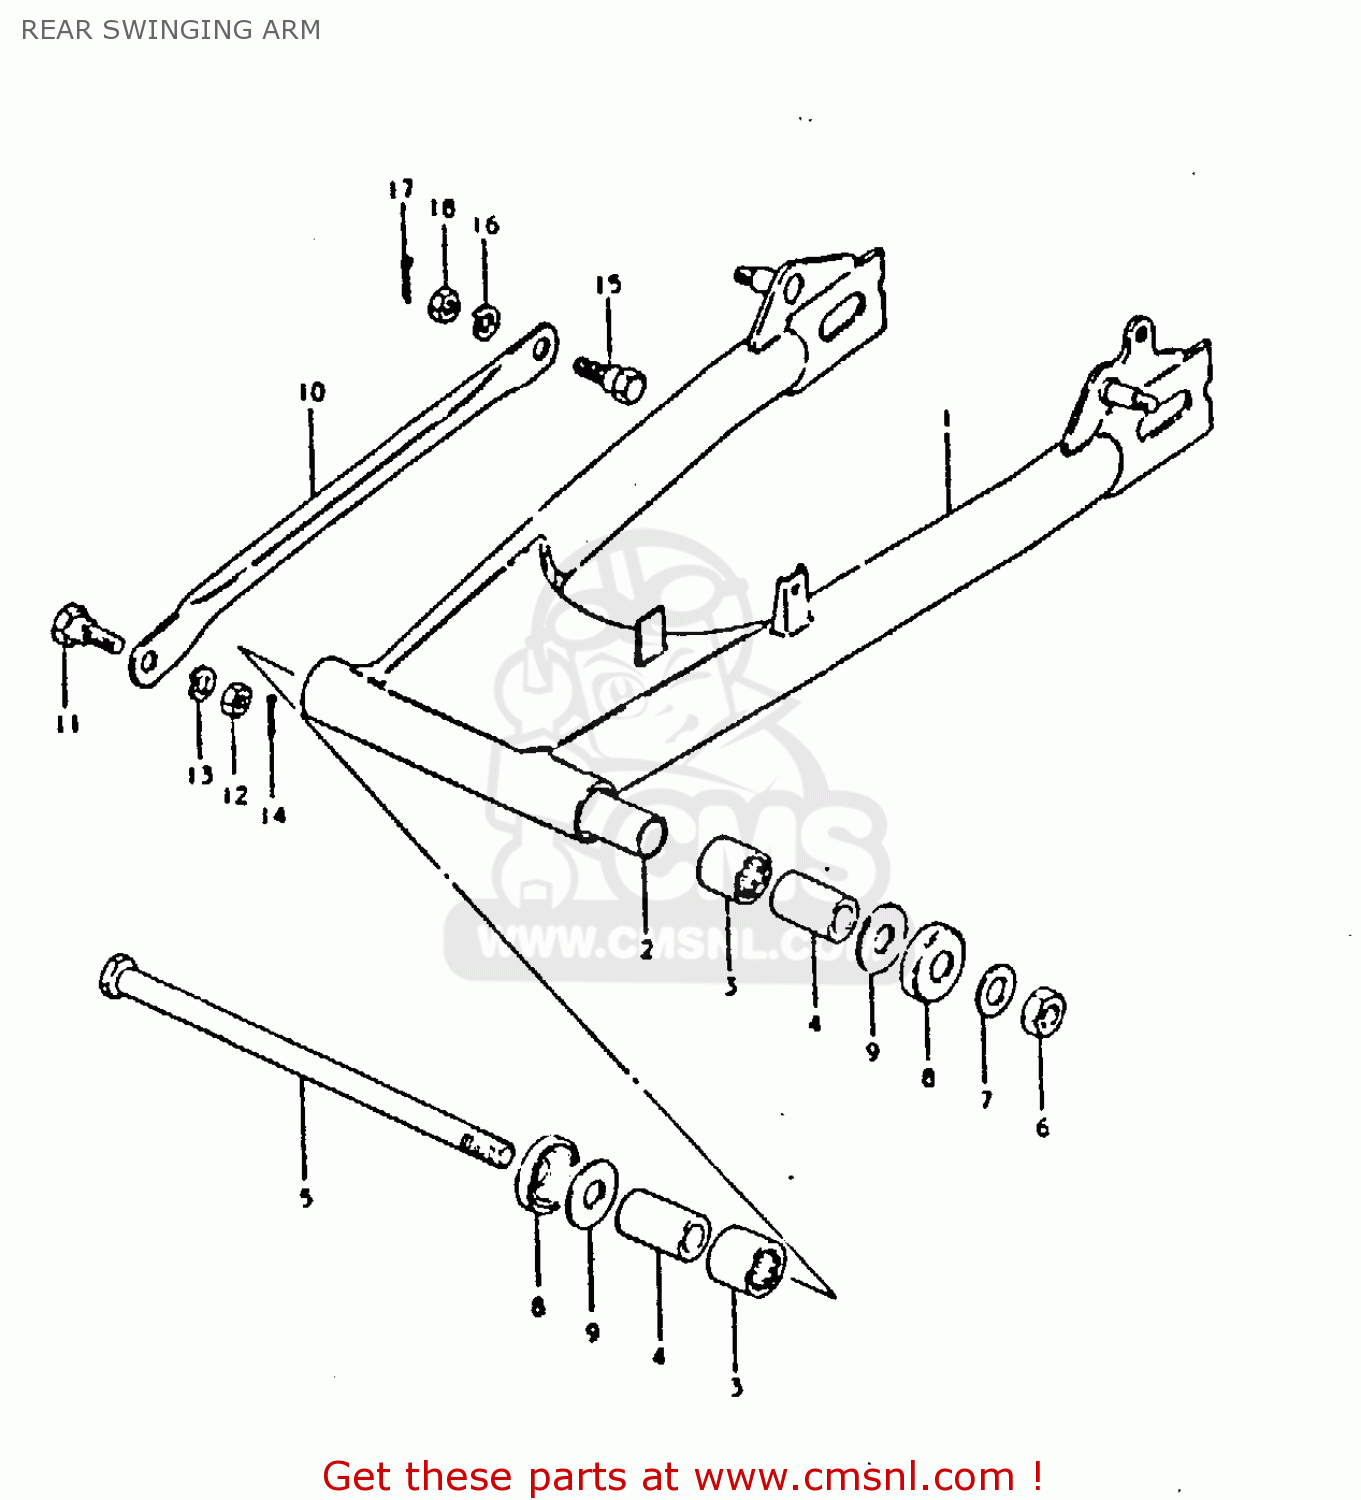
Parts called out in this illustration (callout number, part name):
1	SWING ARM ASSEMBLY,REAR
2	SPACER,SWINGINGARM CTR
3	BEARING(22X29X30)
4	SPACER,RR SWGARM PIVOT
5	SHAFT,REAR SWING ARM
6	NUT 14MM
7	WASHER
8	CVR,RR SWGARM DUST SEAL(OD:40)
9	WASHER(14.2X34X1)
10	TORQUE LINK,REAR
11	BOLT(10X24.5)
12	NUT
13	LOCK WASHER
14	PIN
15	BOLT(10X31)
16	LOCK WASHER
17	PIN
18	NUT
